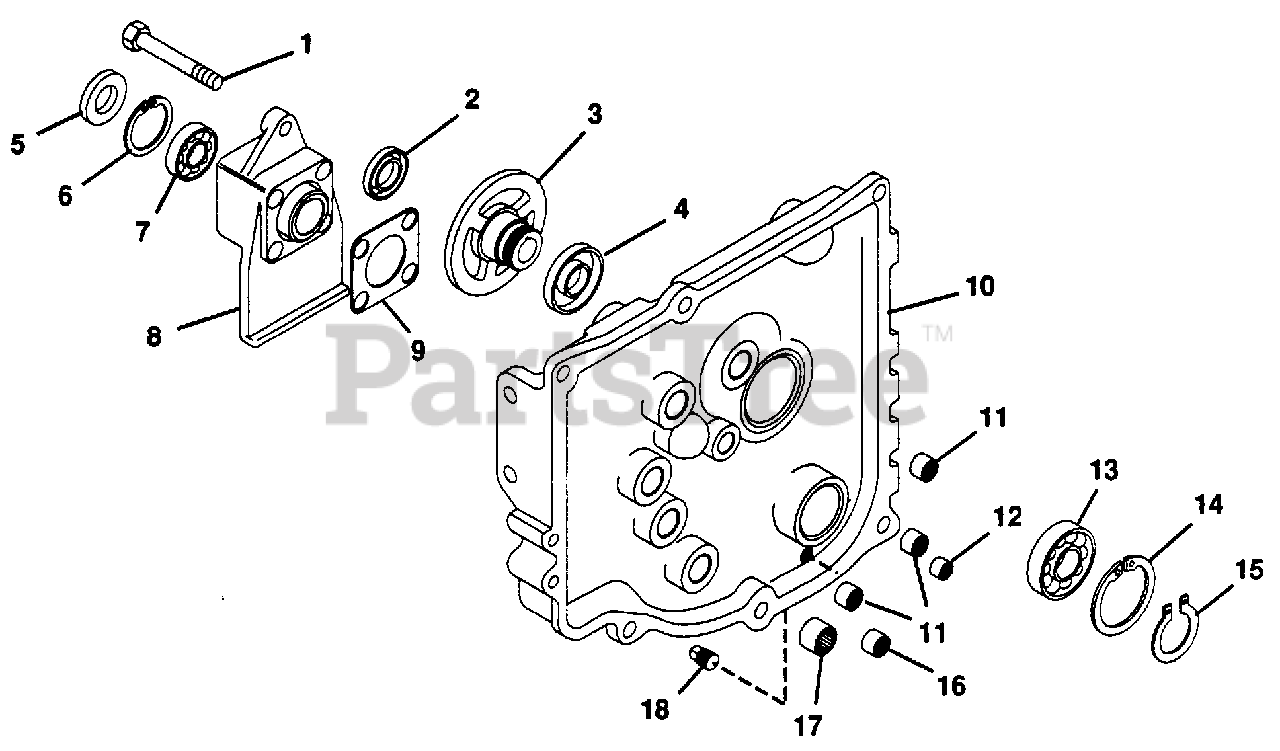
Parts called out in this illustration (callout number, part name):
1	BOLT, HEX 1/2-13X3.25
2	SEAL, OIL .750X1.625X.250
3	HUB, CLUTCH
4	SEAL, OIL
5	SEAL, OIL AXLE
6	RING, RETAINING .08 THICK
7	BEARING, BALL SEALED
8	RETAINER, AXLE BEARING
9	GASKET(SERVICE ONLY)
10	ASSEMBLY, TRANSMISSION COVER(INCLUDES ITEMNUMBERS 3,4 AND 11 THROUGH 17.)
11	BEARING, NEEDLE .75X1X.75
12	BEARING, NEEDLE .625X.812X.75
13	BEARING, BALL
14	RING, RETAINING
15	RING, RETAINING 1.969 SHAFT
16	BEARING, NEEDLE .75X1X.75
17	BRG, NEEDLE 1.000X1.250X.750
18	PLUG, PIPE 3/8
